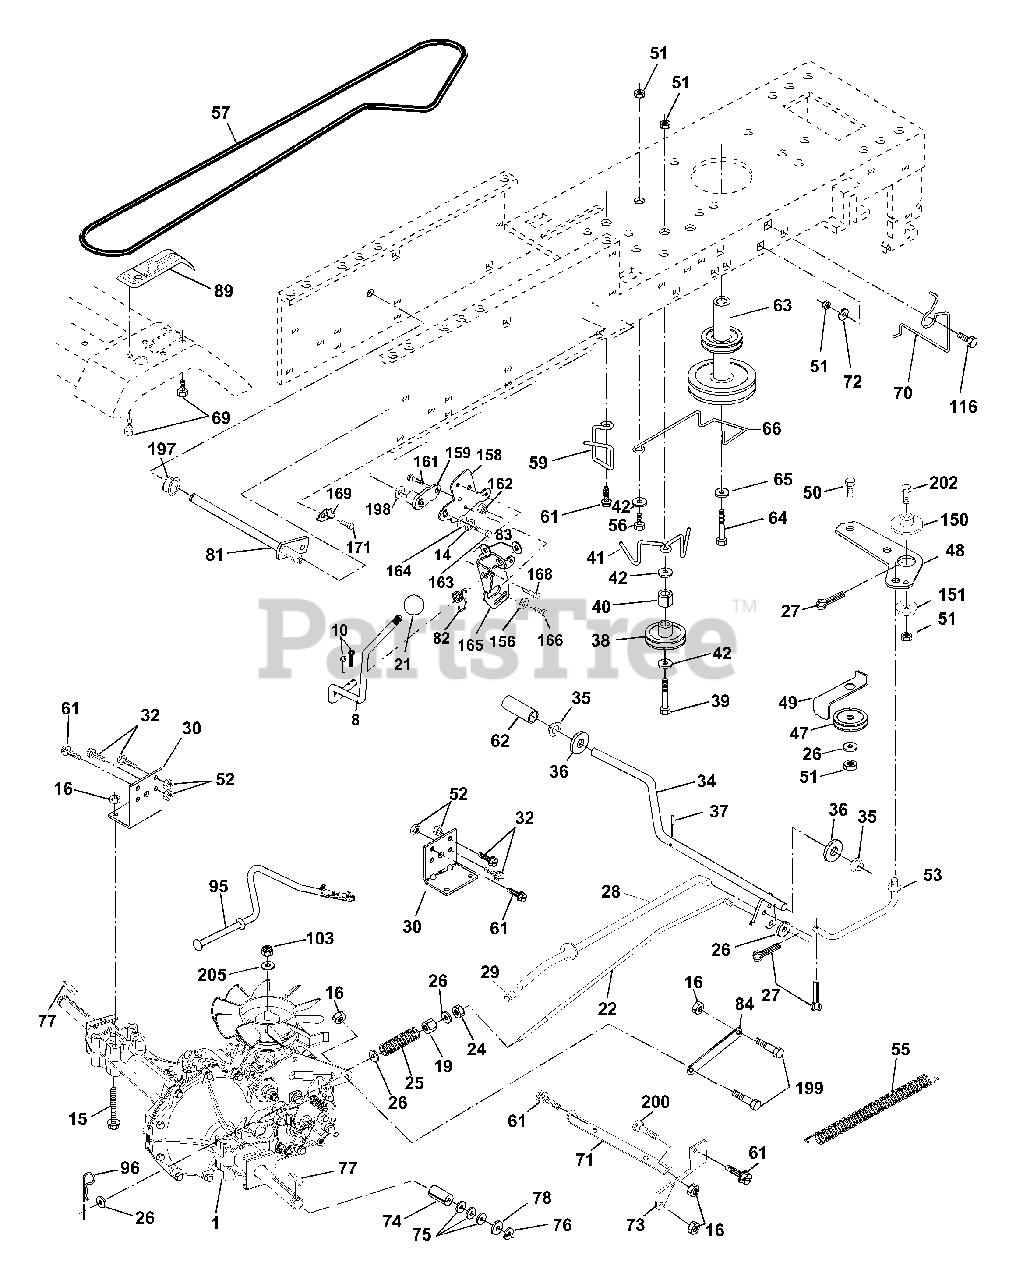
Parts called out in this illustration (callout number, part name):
10	Pin Cotter 1/8 x 1 CAD
14	Washer Lock Hvy. Helical
15	Bolt, Hex FLGHD 5/16-18 Gr. 5
16	Nut Lock Hex W/Ins 5/16-18 Unc P
19	Nut Lock Hex W/Wsh 3/8-16 Unc
21	Knob
22	Rod, Brake Hydro
24	Nut
25	Spring, Brake Rod
26	Washer
27	Pin Cotter 1/8 x 3/4 CAD.
28	Rod, Parking Brake
29	Cap, Parking Brake
30	Bracket, Transaxle
32	Bolt Hex Hd 5/16-18 Unc x 3/4
34	Shaft, Foot Pedal
35	Bearing, Nylon
36	Washer
37	Pin, Roll
38	Pulley, Idler, Flat
39	Bolt
40	Spacer, Split
41	Keeper, Belt Retainer
42	Washer 13/32 x 13/16 x 12 Gauge
47	Pulley, Idler, V-Groove
48	Bellcrank Clutch Grnd Drv STL
49	Retainer, Belt
50	Bolt
51	Nut Crownlock 3/8-16 UNC
52	Nut Crownlock 5/16-18 UNC
53	Link, Clutch
55	Spring, Return, Clutch
56	Bolt Fin Hex 3/8-16 UNC x 1-1/4
57	V-Belt
59	Keeper, Center Span
61	Screw 3/8-16 x 3/4
62	Cover, Pedal
63	Pulley, Engine
64	Bolt, Hex
65	Washer
66	Keeper Belt Engine
69	Screw Hex Wsh Hi-Lo 1/4-1/2 unc
70	Keeper Belt Engine
71	Strap Torque Lh
72	Washer 13/32 x 1-1/4 x 12 Gauge
73	Strap Torque Rh
74	Spacer, axle
75	Washer 25/32 x 1-1/4 x 16 Gauge
76	E-Ring
77	Key, Square
78	Washer 25/32 x 1-5/8 x 16 Gauge
81	Shaft Asm. Cross
82	Spring Torsion
83	Washer 17/32 x 3/4 x 16 Ga.
84	Link, Transaxle
89	Console, Shift
95	Control Asm Bypass Hydro
96	Retainer Spring 1" Zinc/Cad
103	Nut, Hex, Jam Toplock 1/2-20 UNF
116	Bolt Rdhd Sq. Neck 3/8-16 x 1.25
150	Bushing Bellcrank Grd Drive
151	Washer 13/32 x 2 x 10 Ga.
156	Washer Srrted 5/16 ID x 1 x .125
158	Bracket Shift Mount
159	Hub Tapered Flange Shift LT
161	Bolt Rdhd Sqnk 1/4-20 x 3/4 Gr. 5
162	Nut Crownlock 1/4-20 Unc
163	Bolt Hex Fin 1/4-20 Unc x 1 Gr. 5
164	Washer 5/8 x .281 x 10 Ga.
165	Bracket Pivot Lever
166	Screw 5/16-18 x 5/8
168	Bolt Shoulder 5/16-18 x .561
169	Plate Fastening LT
171	Screw Thdrol 3/8-16 x 1/2
197	Nyliner Snap-In 5/8" ID
198	Washer Nyl 7/8ID x .105"
199	Bolt Shoulder 5/16-18 Unc
200	Bolt Rdhd Sqnk 5/16-18 unc x 1
202	Bolt Carr Sh 3/8-16 x 1-1/2 Gr. 5
205	Washer 17/32 x 1 x 16 Ga.
